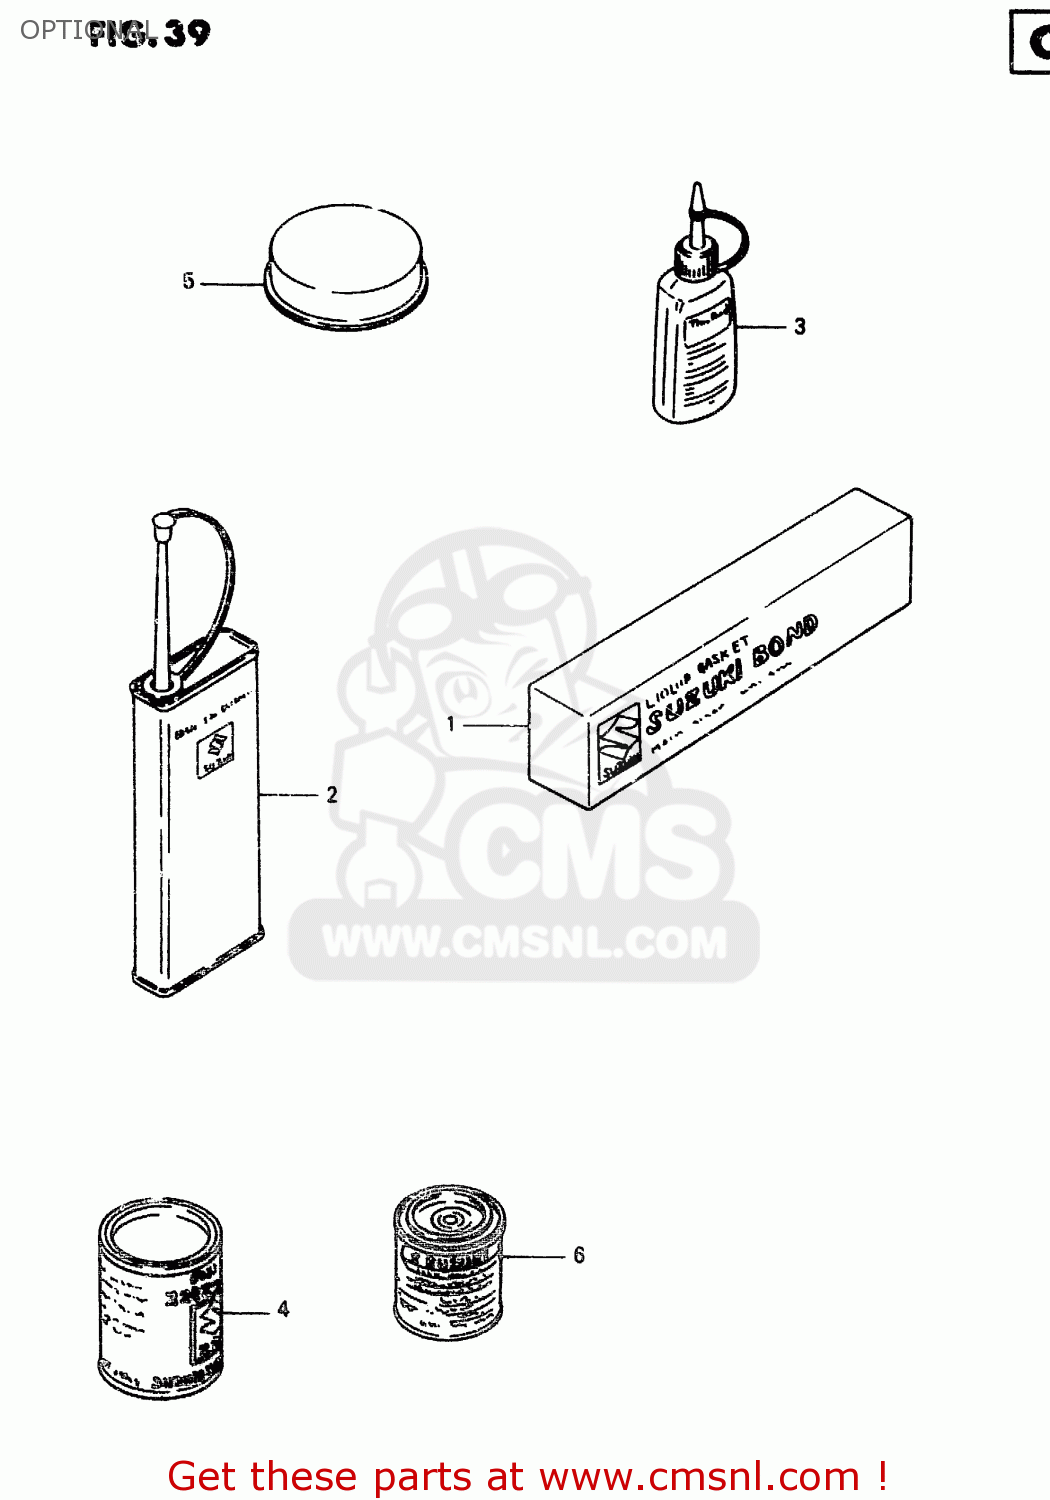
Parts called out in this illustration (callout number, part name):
1	BOND 1104
2	THREAD LOCK NO.1401 CLEAR 200G
3	THREAD LOCK NO
4	GREASE(C)EP2 LITHIUM 150G
5	GREASE,PBC FOR BRK PAD 20G
6	PAINT,BLACK
